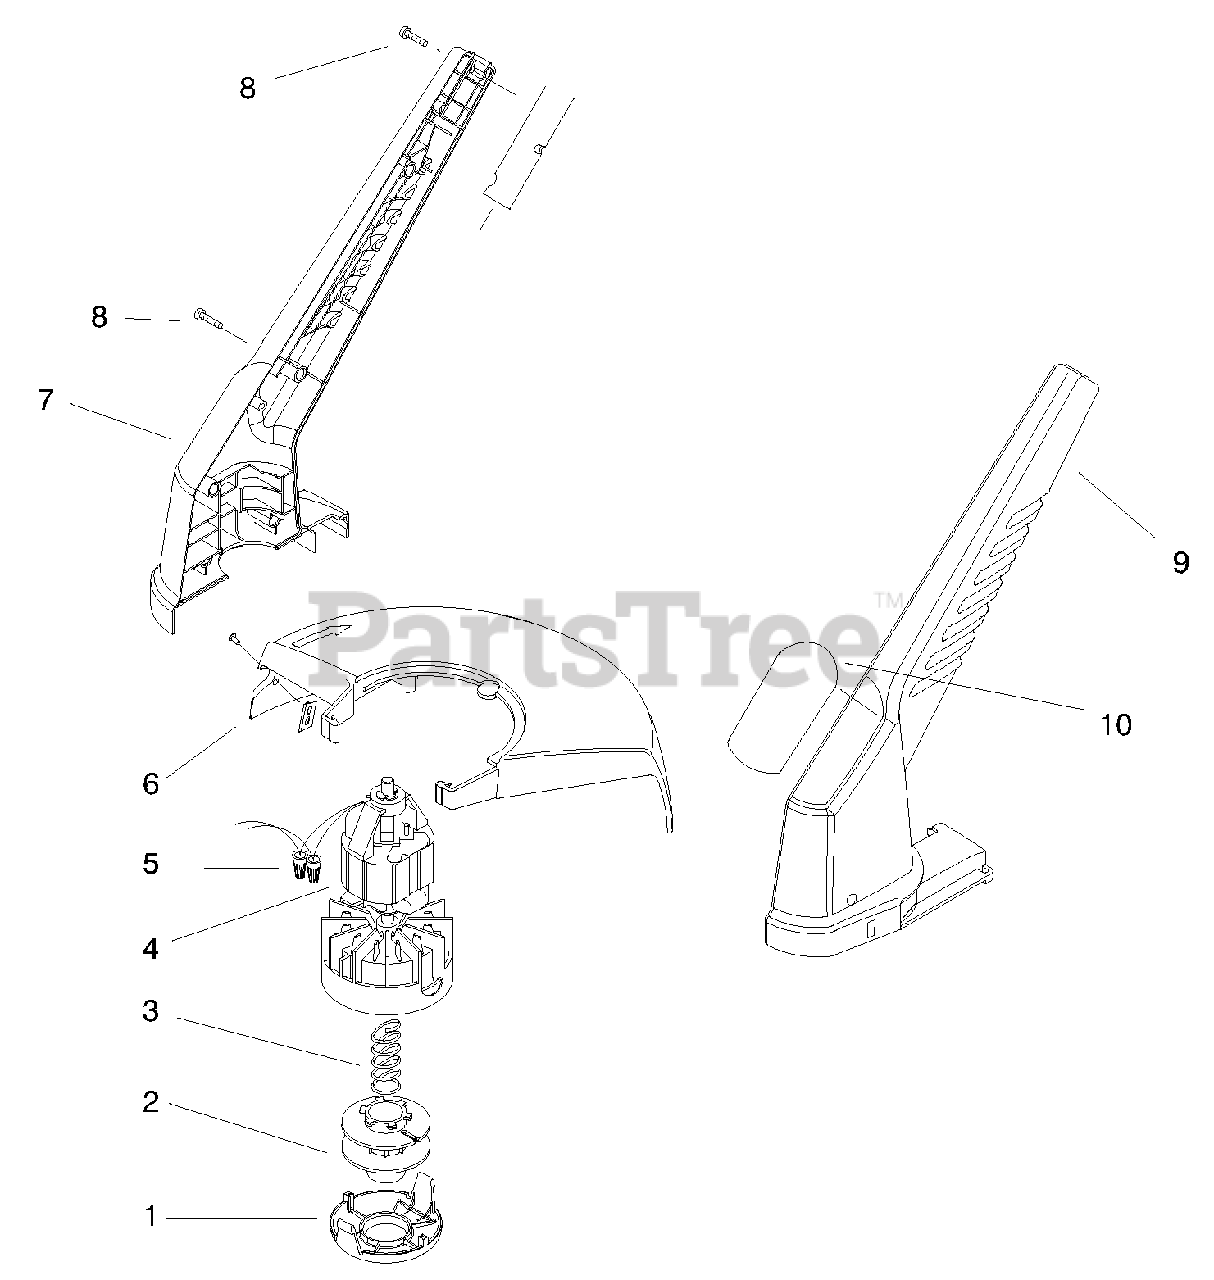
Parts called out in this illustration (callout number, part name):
4	Motor Assembly
5	Connector-Wire Nut
6	ASM-Shield-11"
7	Housing R.H.
8	Screw-Pan Hd.
9	Housing L.H.
10	Decal-11" Trimmer
